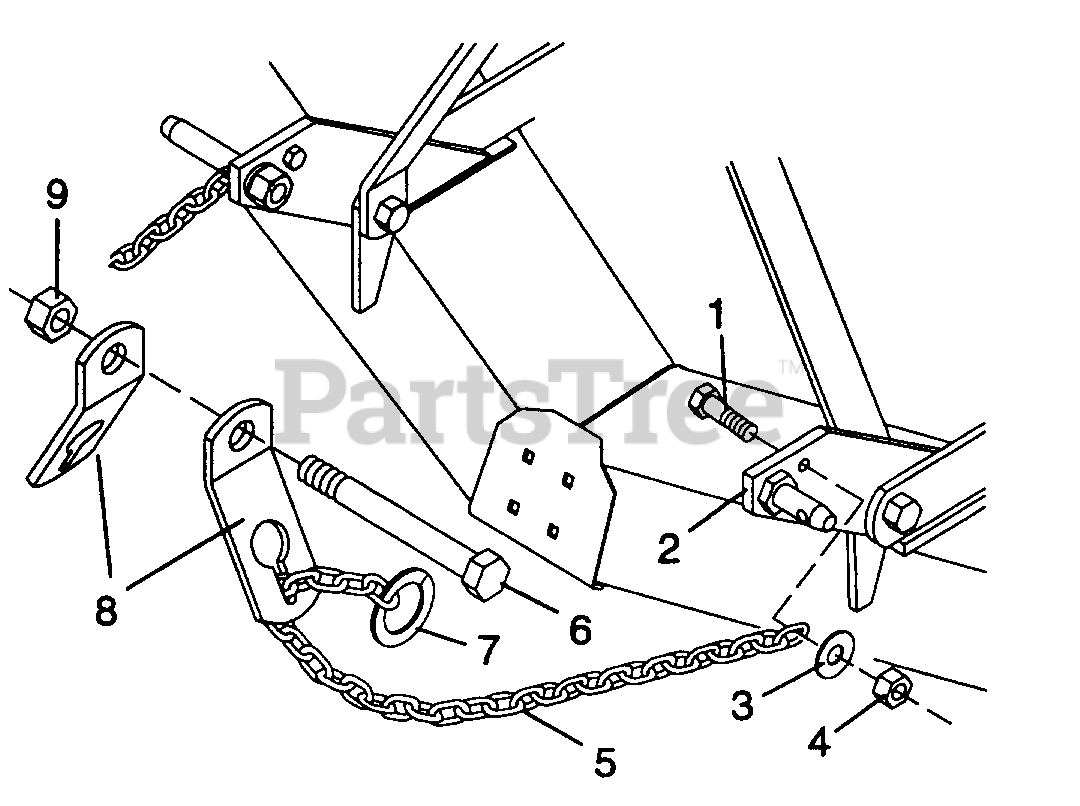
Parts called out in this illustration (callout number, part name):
1	7/16 NC x 1-1/2 Hex head cap screw GR5
3	7/16 Standard flat washer
4	7/16 NC Hex locknut
5	Chain, 1/4 proof coil x 32.56
6	3/4 NC x 6 Hex head cap screw GR5
7	.048 x 2-1/4 Snap ring
8	Check chain bracket
9	3/4 NC Hex locknut
